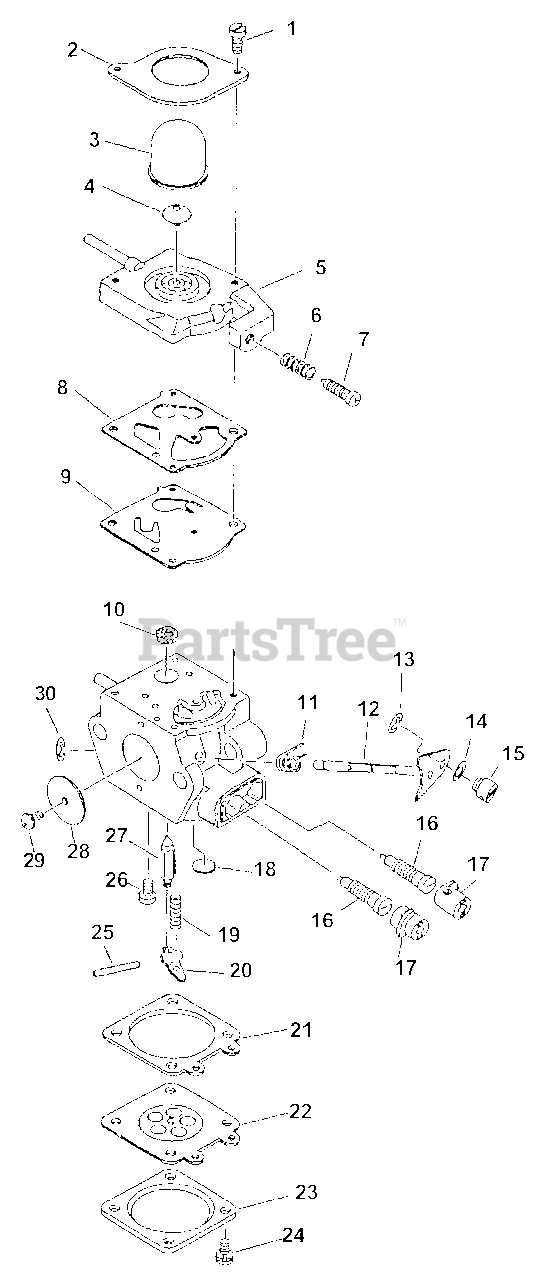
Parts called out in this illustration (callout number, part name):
2	RETAINER, PURGE BULB
3	BULB, PURGE
4	VALVE, CHECK
5	COVER, FUEL PUMP
6	SPRING, IDLE ADJUST
7	SCREW, IDLE ADJUST
8	GASKET, PUMP
9	DIAPHRAGM, PUMP
10	STRAINER
11	SPRING, THROTTLE RETURN
12	SHAFT, THROTTLE
16	NEEDLE, MIXTURE
17	CAP, LIMITER
18	PLUG, WELCH
19	SPRING, METERING LEVER
20	LEVER, METERING
21	GASKET, METERING
22	DIAPHRAGM, METERING
23	COVER, METERING DIAPHRAGM
24	SCREW
25	PIN, METERING LEVER
26	SCREW
27	VALVE, INLET NEEDLE
28	VALVE, THROTTLE
30	REPAIR KIT, CARBURETOR
30	DIAPHRAGM/GASKET KIT
